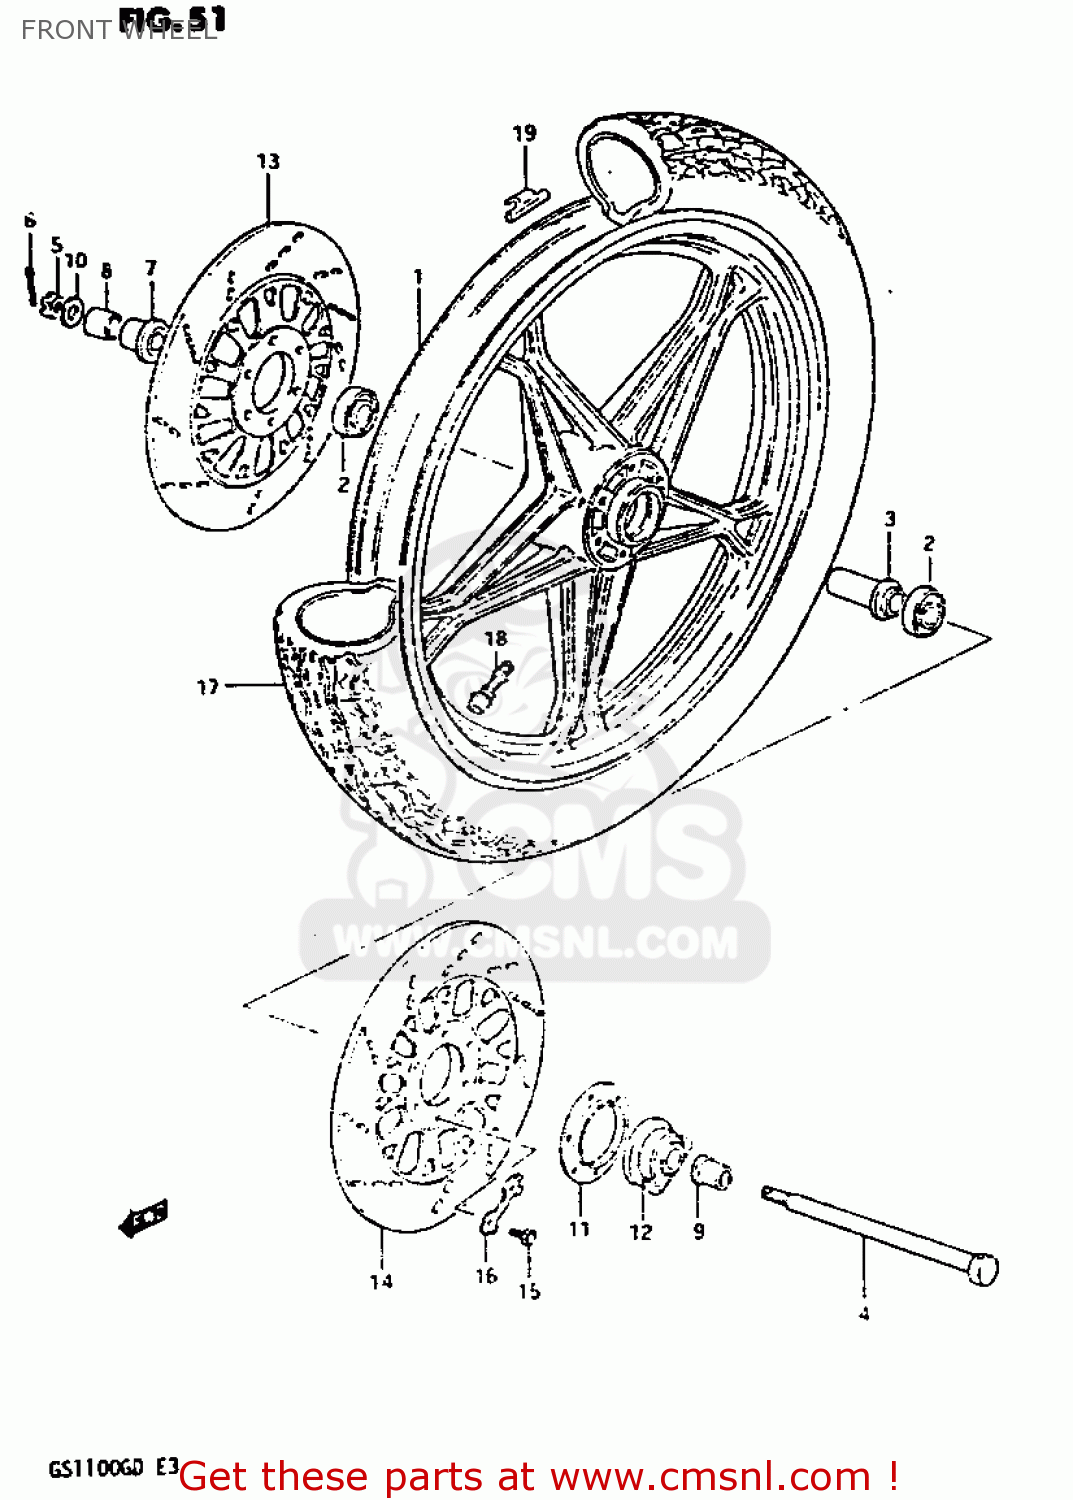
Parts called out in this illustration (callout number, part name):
1	CASTING WHEEL,FRONT 2.15
2	BEARING
3	SPACER,FR HUB BEARING
4	AXLE,FR
5	NUT 12MM
6	COTTER PIN
7	SPACER,FR AXLE,R
8	SPACER,FR AXLE,R
9	SPACER,FR AXLE,L
10	WASHER
11	DUST SEAL,SPEEDOMETER GEAR BOX
12	BOX ASSY,SPEEDOMETER GEAR
13	DISC,FR BRAKE,R
14	DISC,FR BRAKE,L
15	BOLT(8X25)
16	WASHER
17	TIRE,FRONT
18	VALVE ASSEMBLY,WHEEL RIM,J
19	BALANCER,WHEEL
